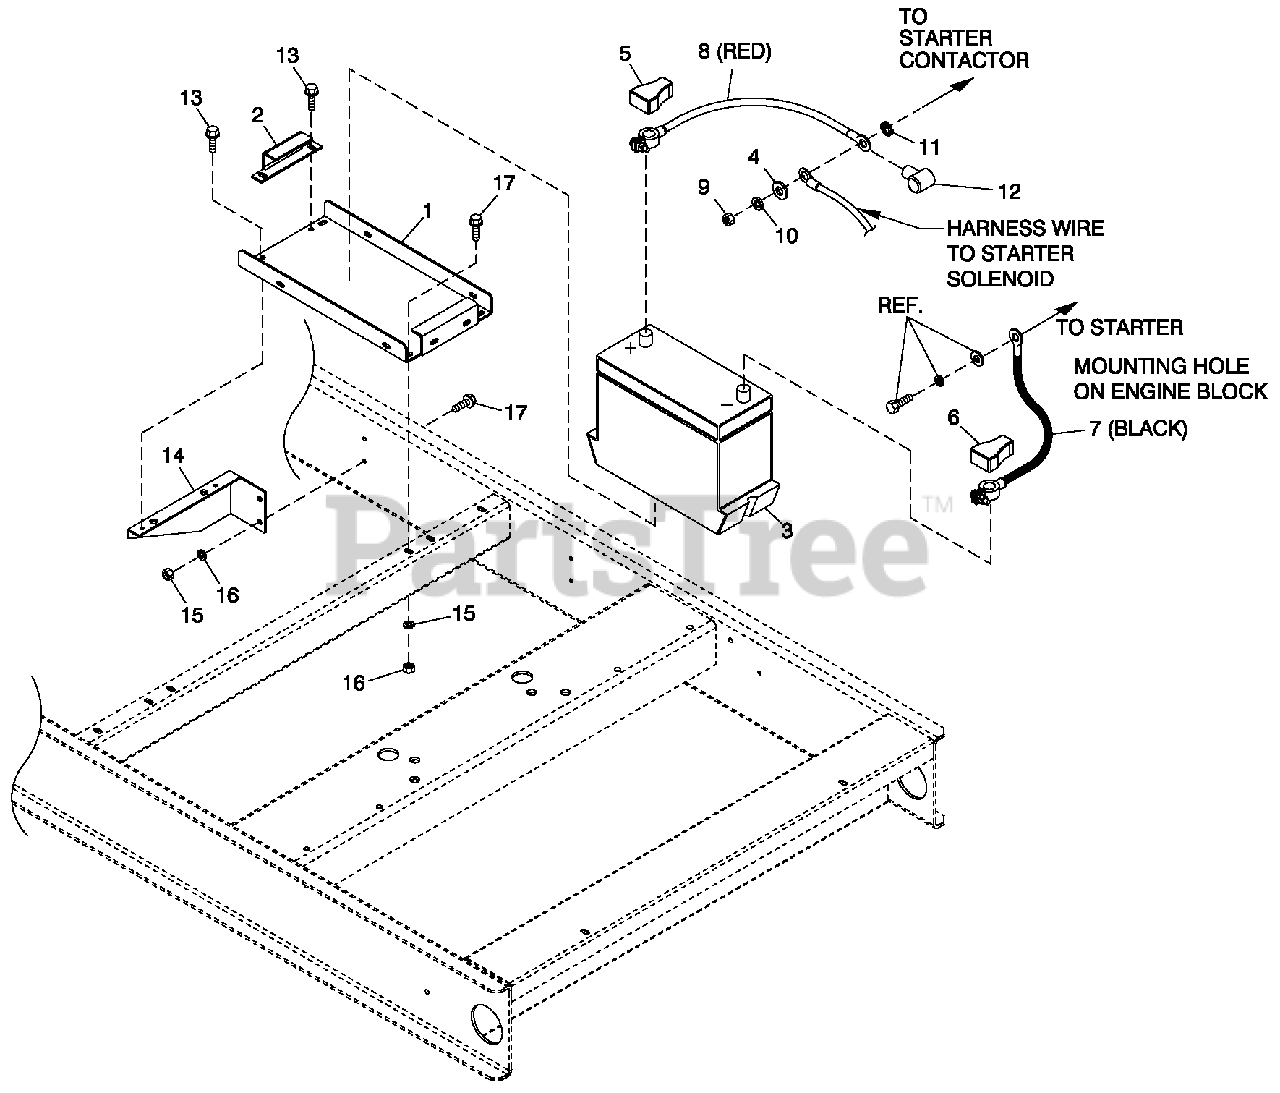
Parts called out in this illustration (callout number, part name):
1	TRAY BATTERY 27F
2	STRAP BATTERY RETAINMENT 27F
3	BATTERY 12VDC 90-AH 27F
4	WASHER FLAT 3/8-M10 ZINC
5	BATTERY POST COVER RED +
6	BATTERY POST COVER BLK -
7	CABLE BATTERY BLK #1 X 18.00
8	CABLE BATTERY RED #1 X 28.00
9	NUT HEX M8-1.25 G8 YEL CHR
10	WASHER LOCK M8-5/16
11	WASHER SHAKEPROOF EXT 5/16 STL
12	BOOT BATTERY CABLE
13	SCREW THF M6-1 X 16 N WA Z/JS
14	SUPPORT BATTERY TRAY
15	WASHER LOCK M6-1/4
16	NUT HEX M6 X 1.0 G8 YEL CHR
17	SCREW HHC M6-1.0 X 20 G8.8
